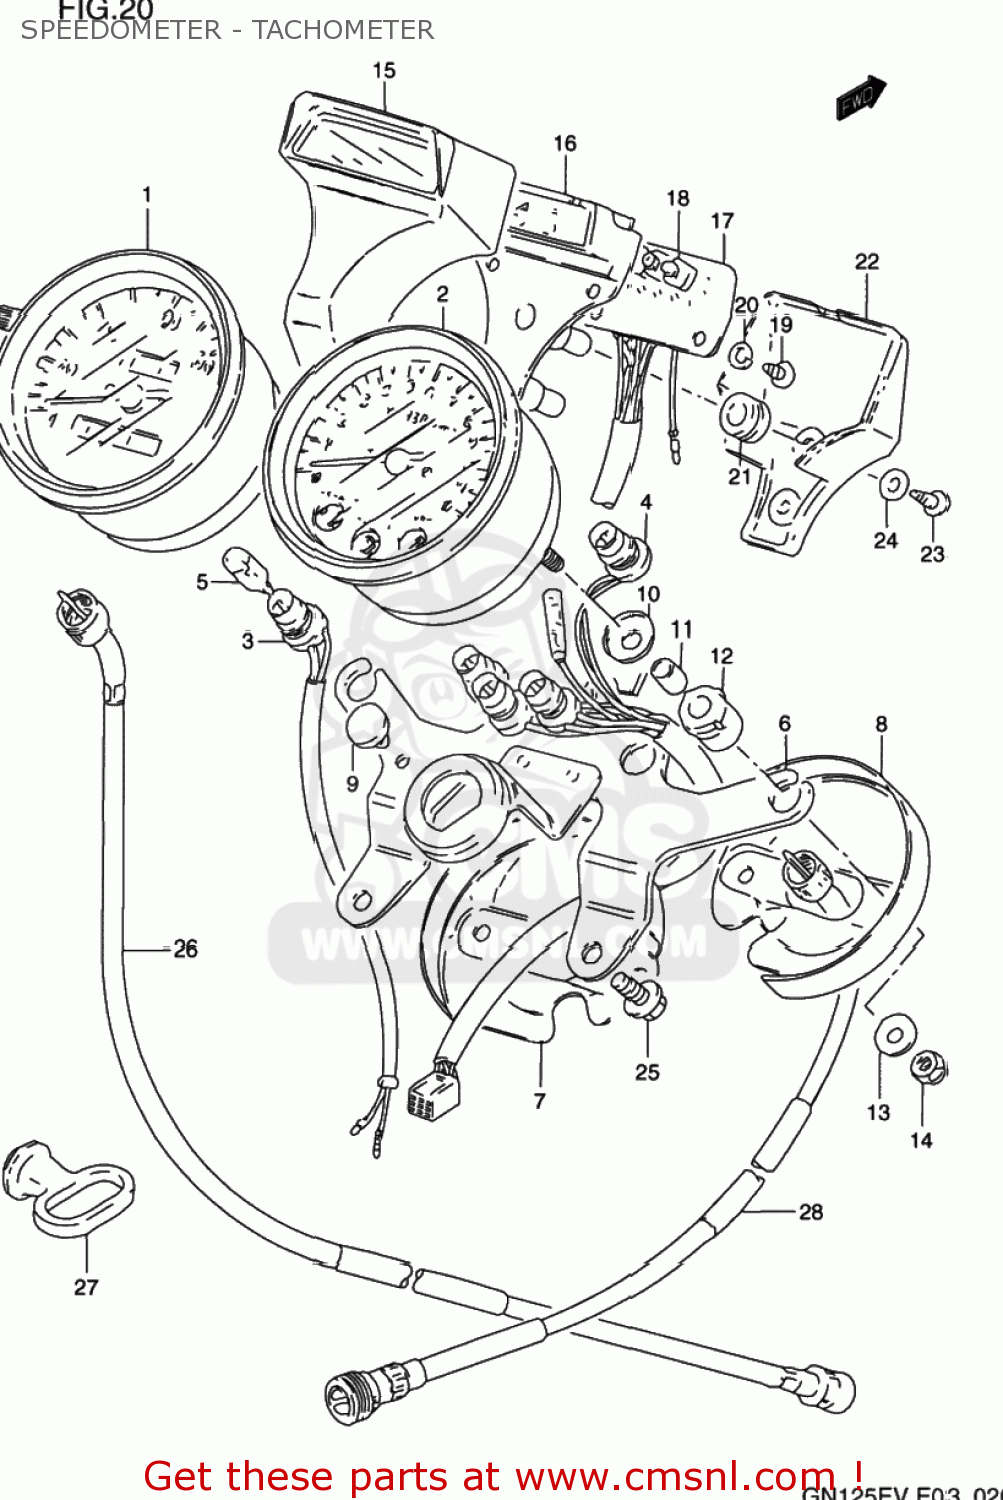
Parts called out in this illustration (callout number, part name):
1	METER,SPEED (KM/MPH)
2	TACHOMETER
3	SOCKET,SPEEDOMETER
4	SOCKET,TACHOMETER
5	BULB(12V3.4W,T10,BF175-01450A)
6	BRACKET,METER
7	UNDER COVER,SPEEDOMETER
8	UNDER COVER,TACHOMETER
9	CUSHION,METER
10	WASHER(5.2X16X1)
11	SPACER,SPEEDOMETER
12	CUSHION,METER
13	WASHER(5.5X16X1.5)
14	NUT
15	PILOT BOX
16	CASE,PILOT BOX
17	INDICATOR,GEAR POSITION
18	BULB(14V1.12W)
19	SCREW
20	WASHER,LOCK
21	CUSHION
22	COVER,LWR
23	SCREW,
24	WASHER
25	BOLT
26	CABLE ASSY,SPEEDOMETER
27	GUIDE,CABLE
28	CABLE ASSY,TACHOMETER
